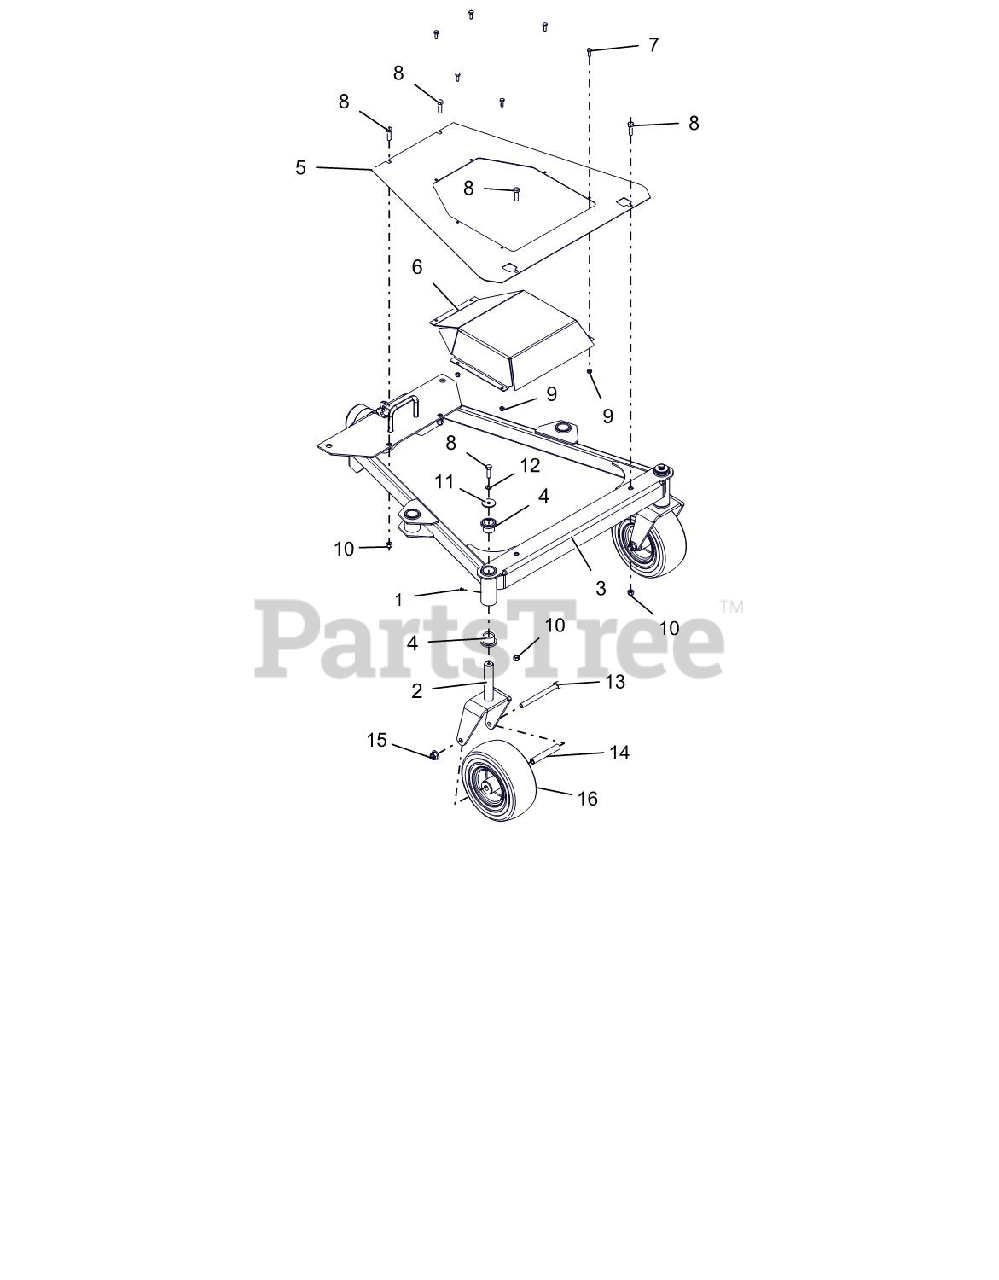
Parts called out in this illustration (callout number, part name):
1	FTG-LUBE .25-28X.256 SST
2	WLDT, FRONT WHEEL FLWLK GRVLY
3	WLDT, FRAME CARRIER 36" (RED)
4	BRG, FLG 1.00 X 1.25 X 1.00
6	WLDMT, COVER GB
7	BLT, HEX .25-20X.75 GR5 ZC120
8	BLT, HEX .38-16X1.25 G5 ZCC
9	NUT,NYL .25-20 G5 ZCC
10	NUT,NYL .38-16 G5 ZCC
11	WSHR-FL-STL .380X1.50X.125ZC
12	WSHR-LK .38X.094 REG ZC120
13	BLT,HEX .50-13X5.50 G5 ZCC
14	TUBE, CASTER AXLE
15	NUT,LK-NYL-FLG .50-13 G5ZC120
16	ASM, WHL/TIRE 9X3.5-4 CAREFREE
